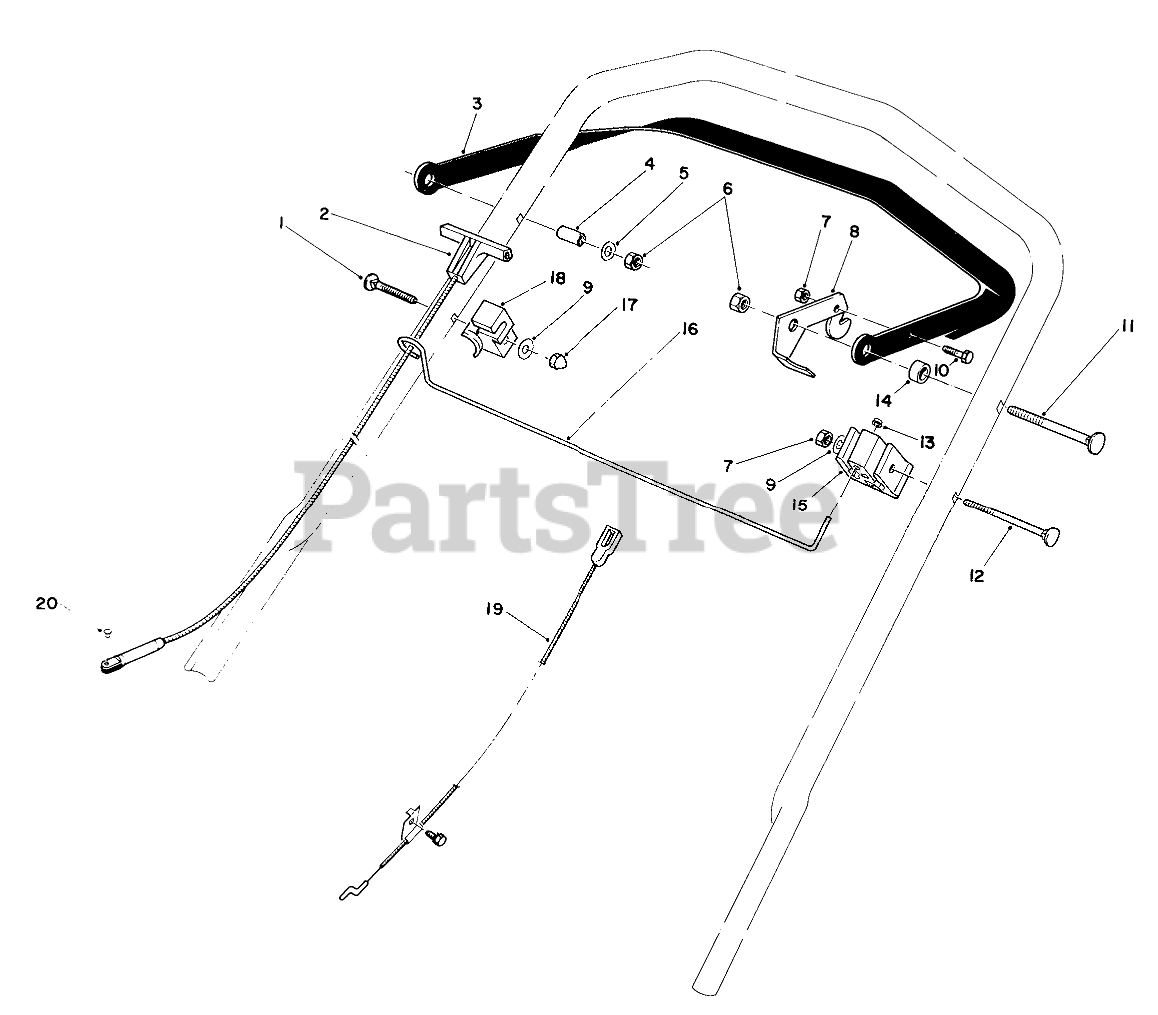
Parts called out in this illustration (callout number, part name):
1	SCREW-HANDLE
2	Rope-Starter
3	Bar-Control
4	Spacer
5	WASHER-PLAIN
6	NUT-LOCK, NI
7	NUT-LOCK, NI
8	Lever-Control
9	WASHER-FLAT
10	SCREW-HH
11	5/16-18 X 2 HNDLE SCREW
12	SCREW-HANDLE
13	NUT-SPEED
14	Nylon Spacer
15	SUPPORT-CABLE
16	ROPE ROD PLATED
17	NUT-CAP
18	ROD CATCH
19	BRAKE CABLE
